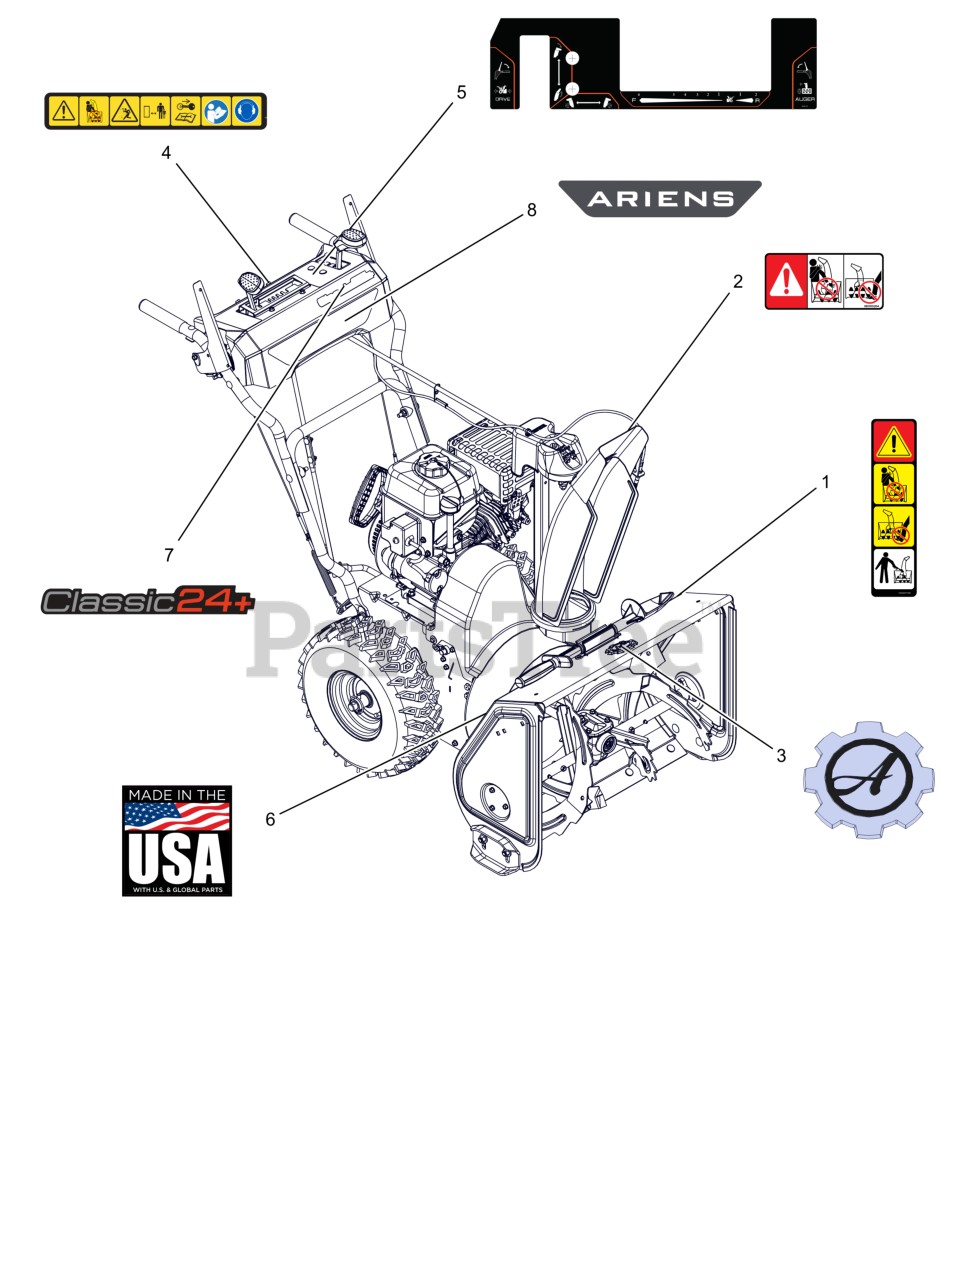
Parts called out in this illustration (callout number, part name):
1	DECAL, DANGER - ROTATING PARTS
2	DECAL, DANGER
3	DECAL, ARIENS - GEAR BADGE
4	DECAL,DASH - SAFETY
5	DECAL,CONTROL-COMP REMOTE
6	DECAL, MADE IN USA
7	DECAL, DASH - CLASSIC 24 PLUS
8	DECAL, DASH BRAND - ARIENS PB
